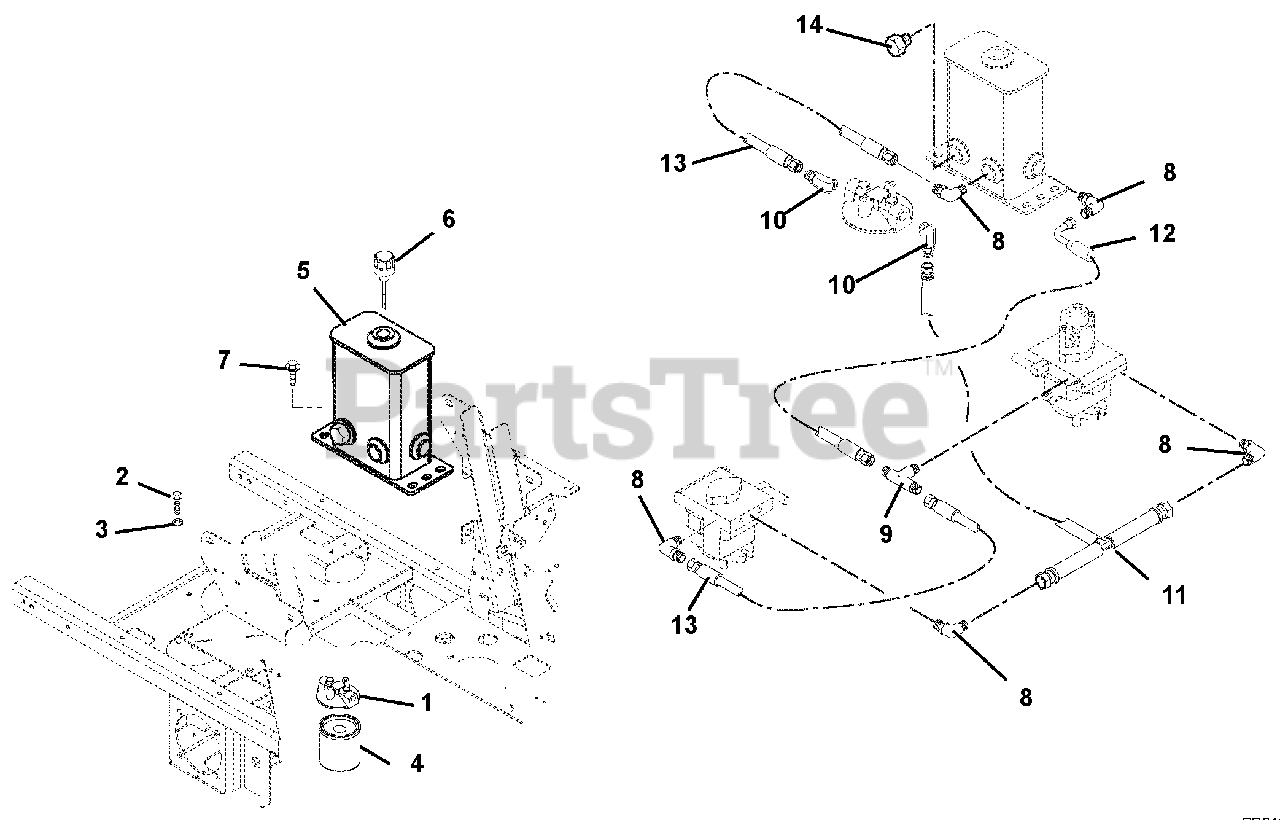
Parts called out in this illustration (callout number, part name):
1	Head, Filter
2	Bolt, Hex .25-20 x .50 Grade 5
3	Washer, Locking .25 x .062
4	Oil Filter
5	Weldment, Hydraulic Tank
6	Hydraulic Tank Dipstick
7	Screw, Tapping .38-16 x .75 Hex Washer Head
9	Fitting, Hydraulic Tee
10	Fitting, Hydraulic 45°
11	Fitting, Tee Assembly, .50
12	Hose, Hydraulic
13	Hose, Hydraulic
14	Plug, Hex, .75-16 O-Ring
